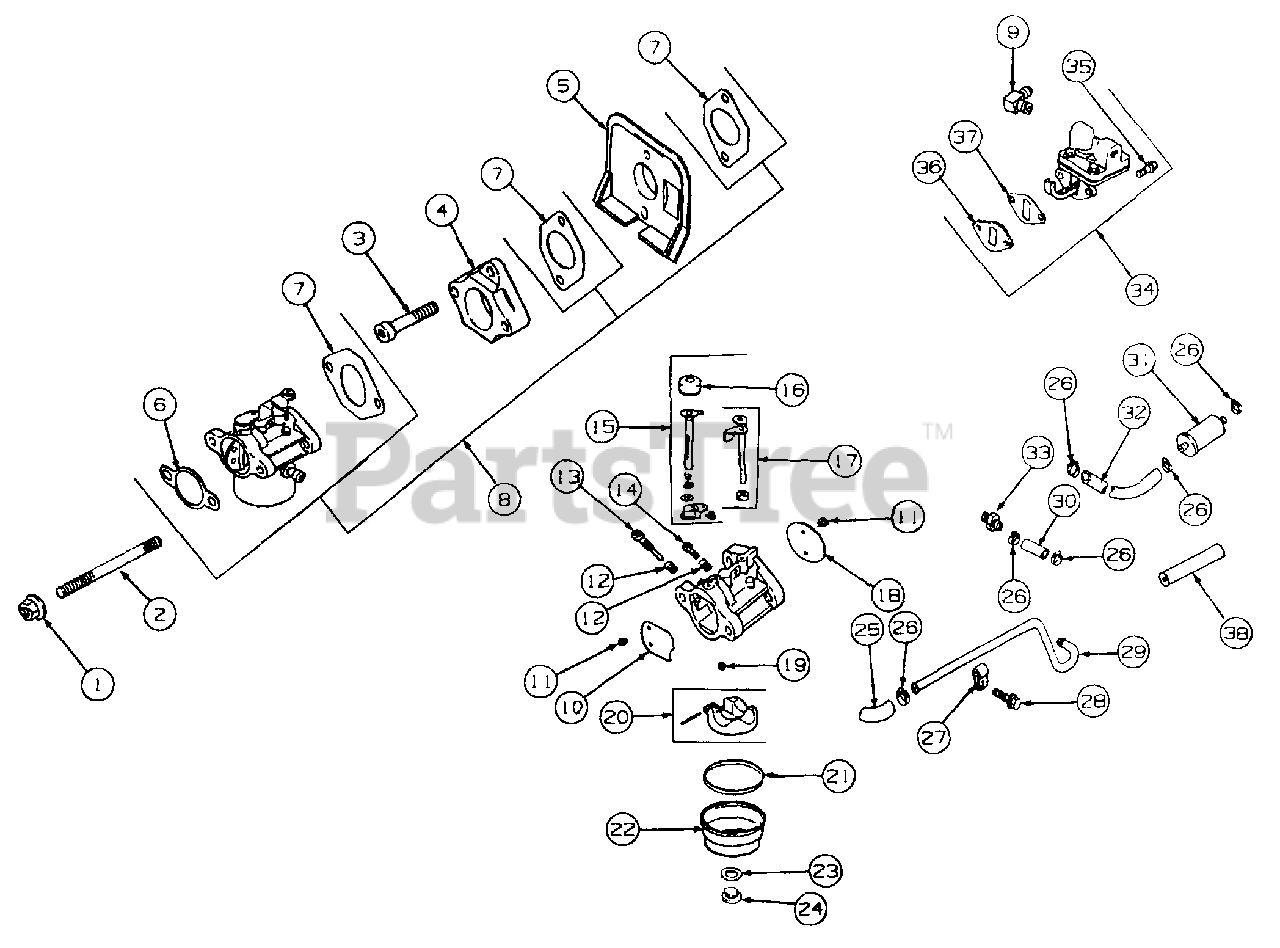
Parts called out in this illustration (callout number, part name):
1	Nut, Hex Flange, M6 x 1.0
2	Stud, Carburetor, M6 x 1.0 x 116
3	Screw, Socket Cap, M6 x 1.0 x 35
4	Adapter, Carburetor
5	Deflector, Heat
6	Gasket, Air Filter
7	Gasket, Carburetor
8	Kit, Carb w/Gskts
9	Connector, Hose, 90°.
10	Plate, Choke
11	Screw, Choke & Throttle Plate
12	Spring, Idle Fuel & Speed Adj
13	Needle, Idle Fuel Adj
14	Screw, Idle Speed Adj
15	Kit, Choke Shaft Repair
16	Cap, Choke Lever
17	Shaft, Throttle w/Seal
18	Plate Throttle
21	Gasket, Bowl
23	Gasket, Bowl Retaining Screw
24	Screw, Bowl Retainer
25	Line,90° Fuel
26	Clamp, Fuel Line
28	Screw, Hex Flange, M5 x .8 x 10
29	Line, Metal Fuel
30	Line, Fuel, 1 1/4
31	Filter, Fuel
32	Line, Fuel, 5"
33	Connector, Straight Hose
34	Kit, Fuel Pump
35	Screw, Hex Flange, M6 x 1 x 20
36	Spacer, Fuel Pump
37	Gasket, Fuel Pump
38	Insulation Fuel Line
